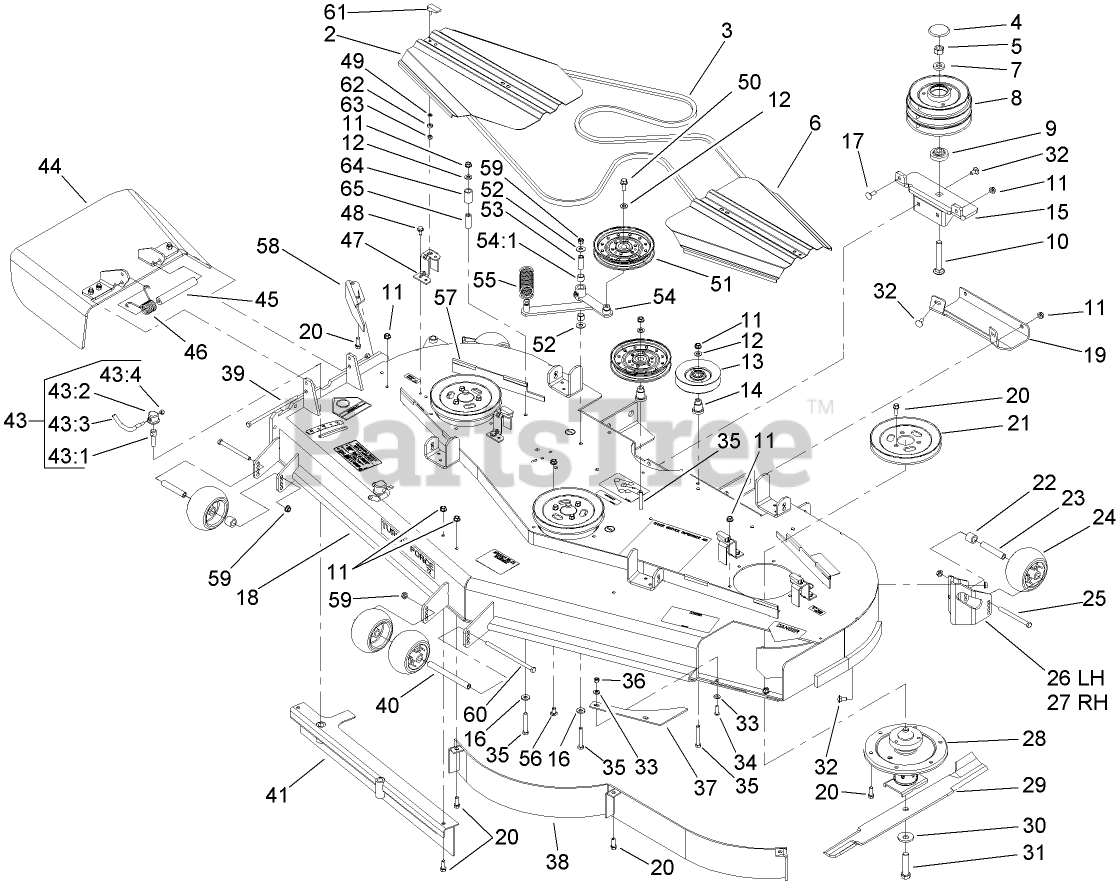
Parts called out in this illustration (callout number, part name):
2	COVER-BELT
3	BELT-V
4	CAP-PLASTIC
5	NUT-HEX
6	COVER-BELT
7	SPACER
8	PULLEY AND BEARING ASM
9	SPACER-FLANGED
10	BOLT-CARRIAGE
11	NUT-HHF, WHIZ
12	WASHER-FLAT
13	PULLEY-IDLER
14	MOUNT-PULLEY
15	MOUNTING BRACKET ASM
16	WASHER-BELLEVILLE
17	BOLT-CARR
18	DECK DECAL ASM
19	Plate-Skid
20	SCREW-HWH
21	PULLEY
22	TUBE-SPACER
23	TUBE-SPANNER
24	ROLLER-SCALP, ANTI
25	SCREW-HH
26	MOUNT-WHEEL, LH
27	MOUNT-WHEEL, RH
28	SPINDLE ASM
29	BLADE-HI FLOW, 24.5 INCH
30	Washer-Blade Bolt, Heavy
31	Screw-Cap
32	SCREW-CARR
33	WASHER-SPRING
34	SCREW-HSBH
35	SCREW-HH
36	NUT-LOCK, NI
37	PLATE-TURBO
39	SCREW-HH
40	SPACER-WHEEL
43	LEVER ASM
43:1	Screw-Lock
43:2	CAP-LOCK
43:3	Lever-Lock
43:4	NUT-LOCK, NI
44	RUBBER DEFLECTOR ASM
45	SPACER
46	SPRING-TORSION
47	BRACKET-COVER
48	SCREW-HWHTF
49	WASHER
50	SCREW-HHF
51	Idler-Flat
52	WASHER-FLAT
53	BUSHING
54	IDLER ARM ASM
54:1	SLEEVE-BEARING
55	SPRING-EXTENSION
56	SCREW-CARR
57	STRIP-SEAL
58	BAFFLE-DISCHARGE
59	NUT-LOCK, NI
60	SCREW-HH
61	HANDLE-LATCH, SWELL
62	BUSHING-LATCH, SWELL
63	NUT-LOCK, HH
64	SPACER-RUBBER
65	SPACER-PIVOT, IDLER
